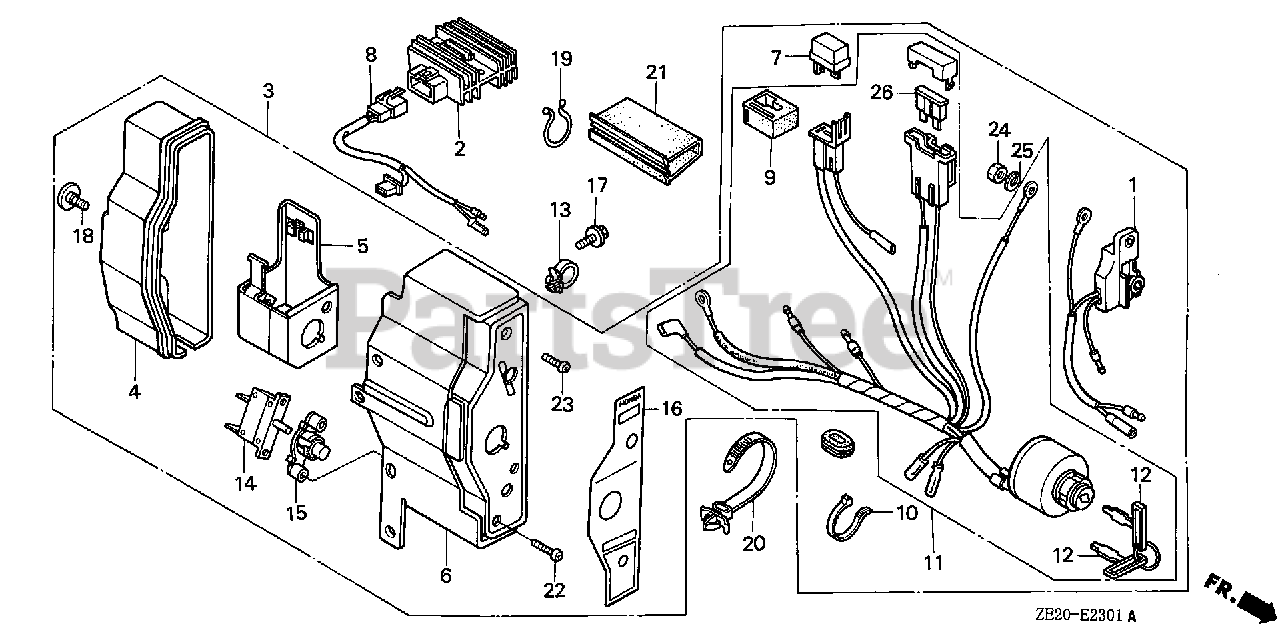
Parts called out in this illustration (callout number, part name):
1	ALERT UNIT, OIL (SEL)
3	BOX ASSY., CONTROL *R8* (ALERT) (BRIGHT RED) (NOT AVAILABLE)
3	BOX ASSY., CONTROL (3A) *R8* (EXP-ALERT) (BRIGHT RED) (NOT AVAILABLE)
4	CASE, CONTROL
5	BRACKET, CASE MOUNTING
6	PANEL, CONTROL *R280* (POWER RED)
7	RECTIFIER ASSY., SILICON (SHINDENGEN)
9	SUSPENSION, CONNECTOR
11	SWITCH ASSY., COMBINATION
11	SWITCH ASSY., COMBINATION (3A-CHARGE)
13	HOLDER, STOP SWITCH WIRE
14	PROTECTOR, CIRCUIT (1.0A)
14	PROTECTOR, CIRCUIT (3.5A)
15	LENS ASSY., PROTECTOR
16	PANEL, CONTROL BOX (EXTERNAL-ALERT) (NOT AVAILABLE)
17	BOLT, FLANGE (6X12) (CT200)
18	SCREW, SPECIAL (6X12)
19	CLIP, PURSE LOCK
20	STRAP, CABLE (118MM) (BLACK)
21	TUBE, FASTENER (30MM)
22	SCREW, PAN (3X12)
23	SCREW, PAN (4X12)
24	NUT, HEX. (4MM)
25	WASHER, SPRING (4MM)
26	FUSE, BLADE (5A)
26	FUSE, BLADE (15A)
